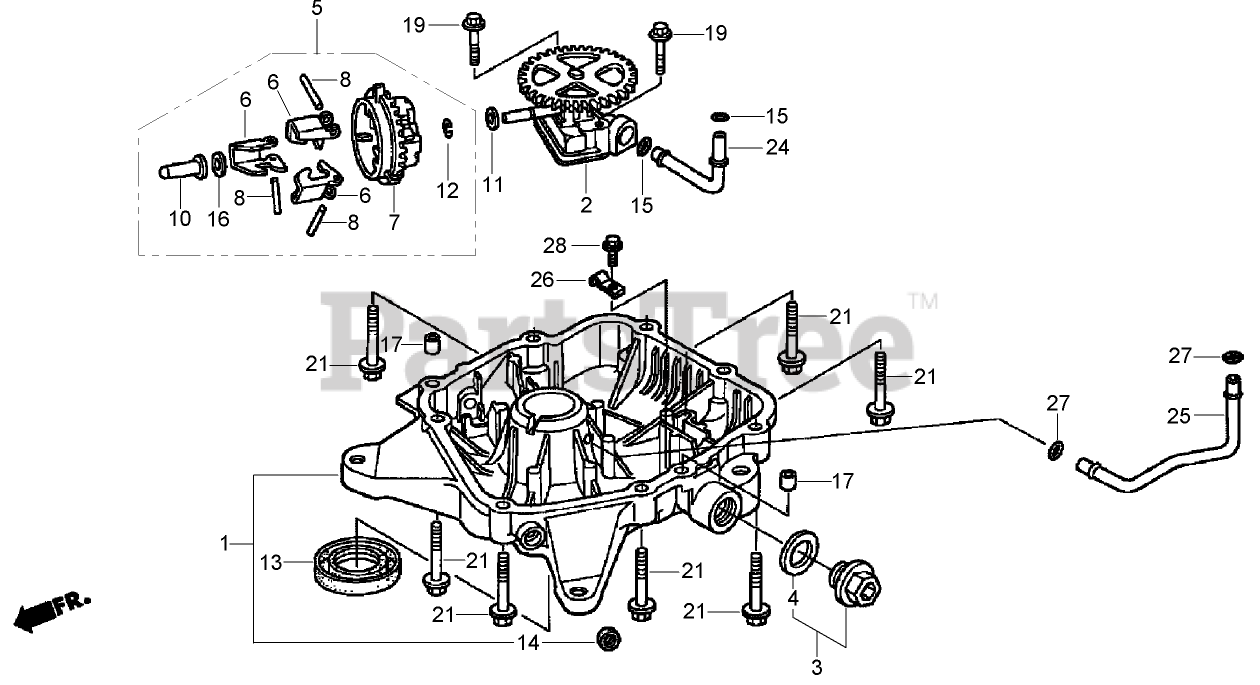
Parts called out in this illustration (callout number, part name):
1	OIL PAN ASM
2	OIL PUMP ASM
3	DRAIN CAP ASM
4	GASKET-CAP, OIL FILLER
5	GOVERNOR ASM
6	WEIGHT-GOVERNOR
7	HOLDER-WEIGHT, GOVERNOR
8	PIN-WEIGHT, GOVERNOR
10	SLIDER-GOVERNOR
11	WASHER (6X16)
12	CLIP-HOLDER, GOVERNOR
13	SEAL-OIL (31X50X8)
14	SEAL-OIL (10X16X4.5)
15	O-RING (7.5X2.3)
16	WASHER-PLAIN (6MM)
17	Pin-Dowel (8X14)
19	BOLT-FLANGE (6X35)
21	BOLT-FLANGE (8X40)
24	PIPE-PUMP, OIL
25	PIPE-SUPPLY, OIL
26	HOLDER-PIPE, OIL
27	O-RING (5.8X2)
28	BOLT-FLANGE (6X12)
